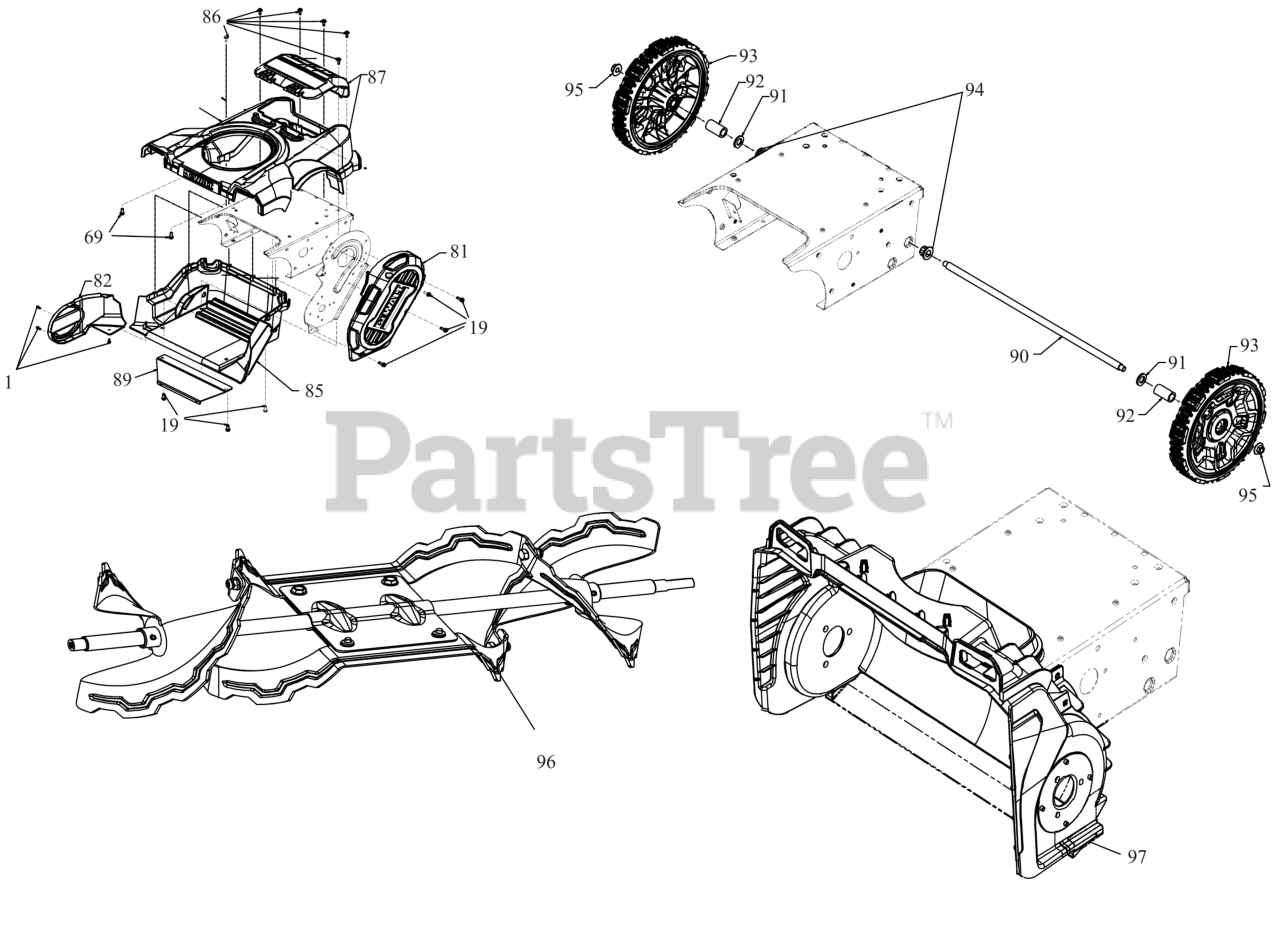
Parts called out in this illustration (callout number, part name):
1	SCREW #8-16 x .50
19	SCREW-TT-1/4 20X0.75-HXINDWSH
69	SCREW 1/4-15 x .750
81	BELT COVER
82	HOUSING COVER (RH)
85	FRAME COVER (BOTTOM)
86	SCREW 1/4-10 x .750
87	COVER
89	SHAVE PLATE BRACE
90	AXLE SHAFT 19.188 LG
91	FLAT WASHER .535 x .930 x .090
92	SPACER .525 X .775X 1.375
93	WHEEL 9X1.5
94	HEX FLANGE BEARING .506ID x .590LG
95	FLANGE LOCK NUT
96	AUGER ASSEMBLY
97	AUGER HOUSING
